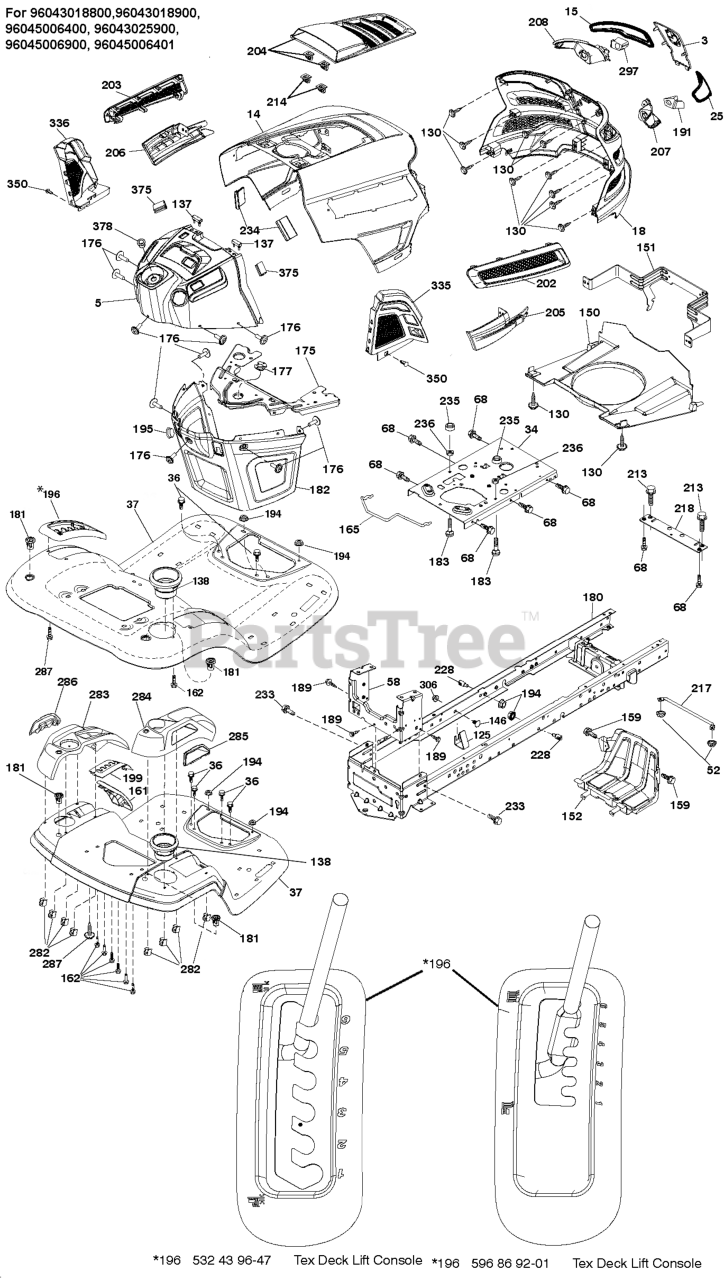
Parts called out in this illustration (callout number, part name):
3	APPLIQUE.SUBASM.GT.HUSQ.II
5	DASHBOARD.UPPER.ASM.GT2.498
5	DASH.UPR.ASSY.GT2.SRVMNDER.PTO
5	DASH
5	Dashes
14	KIT.HOOD.ASM.HUSQ.GT.TEX.668
14	DASH.UPR.ASSY.GT2.SRVMNDER.PTO
15	LENS.HEADLIGHT.LH.GTII.2011
18	GRILLE.SUBSTRATE.2011.
25	LENS.HEADLIGHT.RH.GTII.2011
34	PLATE.ENGINE.WELDED.CHASSIS
36	SCREW 5/16"
37	FENDER.TLT.W/CPH.W/FW.ORANGE
37	FENDER.TLT.FS.W/CPH/FW/RSF.ORN
37	FENDER.TLT.PDL.CNTRL.W/CPH.ORG
58	DRAWBAR UPPER 2PC SMALL FENDER
125	CLIP.FUEL.LINE
137	BUMPER DASH
138	HOLDER.CUP.LT.GREY
146	BOLT.RDHD.SHT.SQNK.3/8-16X5/8
150	AIR.DUCT.GTV.BLACK
151	BRACKET.PIVOT.HOOD.GT.HUSQ.II
152	SHIELD.BROWNING.PNT.GT.V2
159	BOLT.HEX.HD.WASHER.5/16-18X.75
159	SCREW 3/8-16X1
159	SCREW
161	WINDOW.FUEL.LT.HUSQ.TEX.498
162	SCREW.HI-LO.CONSOLE
165	SUPPORT.TANK.REAR.W/TEX
175	PLATE.PNT.CROSSMEMBER.HUSQ/PRE
176	SCREW.#10-24X5/8.RN.QU
177	BUSHING STEERING
180	CHASS.WLDMNT.TL.12GA/2P.48/54
181	BUSHING.MNT.FEND.CRGO.TEX.49
182	DASH.LOWER.COMMON.12V.ADAPTOR
183	BOLT.5/16-18X1-1/4 FULL THD
189	SCREW, 3/8-16X3/4
189	SCREW
189	BOLT.HEX.HD.WASHER.5/16-18X.75
191	INSERT.REFLECTIVE.RH.HUSQ.GTII
194	NUT LOCK HEX FLANGE 5/16-18
195	PLUG.HOLE.DASH.LOWER.12V.BLK
199	PLATE.DECK.LIFT.HUSQ.LT
202	VENT.SIDE.RH.GT.HUSQ.II.
203	VENT.SIDE.LH.GT.HUSQ.II.498
204	VENT.TOP.ASM.HUSQ.GT2
204	VENT.ASM.TORPHD.HUSQGT.LOGO.CL
205	SIDE.TRIM.RH.GT.HUSQ.II
206	SIDE.TRIM.LH.GT.HUSQ.II.GRAY
207	HEADLIGHT.CUP.BEZEL.HUS.GT2.RH
208	HEADLIGHT.CUP.BEZEL.HUS.GT2.LH
213	BOLT
213	SCREW HEXAGON HEAD SCREW 5/16-
214	CLIP.RETAINER.TINNER.
217	ROD.PIVOT.HOOD
218	X-PIECE.HOOD.STOP.NON/
228	STUD.W/"D"ANTI-ROTATION
233	BOLT.SHOULDER
234	BUMPER.HOOD.TEX.HUSQVARNA
235	SPACER FENDER
236	NUT.CENTERLOCK.5/16-
282	CLIP.RETAINER.CONSOLE.LT.HUSQ
283	CONSOLE.DECK.LIFT.R.SDFL.HUSQ
283	CONSOLE.ASM.LFT.RSF.HUSQ.LT
284	CONCOLE.CNTRL.PDL.HUSQ.LT.498
284	CONSOLE.SHFT.PDL.CNTRL.HUSQ.LT
285	CONSOLE INSERT RH
286	CONSOLE.INSRT.LH.HUSQ.LT.BLACK
287	SCREW 1/4X20
297	INSERT.REFLECTIVE.LH.HUSQ.GTII
306	NUT LOCK FLG 3/8-16 UNC
335	COVER.LOWER.DASH.RH.BLACK
336	COVER-LH.LOWER.DASH.GT2.BLACK
350	CLIP.X-MAS.TREE
375	BUMPER CLIP-ON. DASH 1"
378	BUSHING FLANGE; PLASTIC
